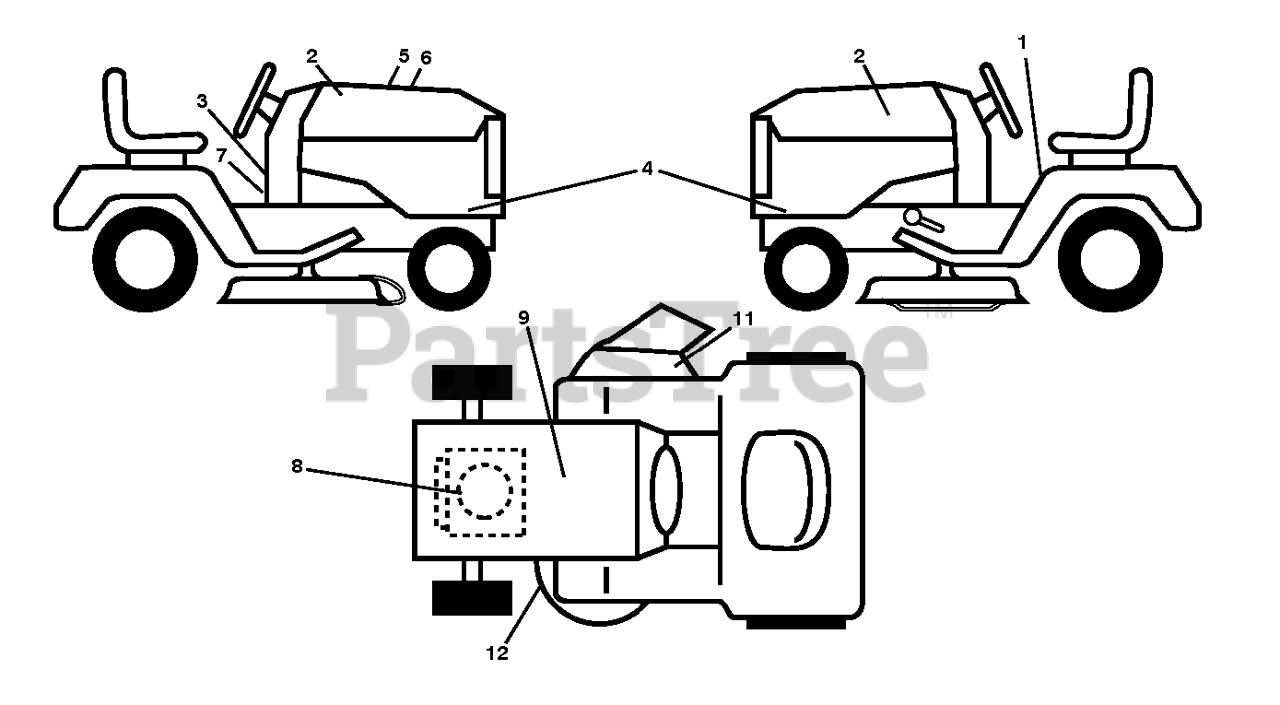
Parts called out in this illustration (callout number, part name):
1	DECAL.FENDER.WARNING
2	DECAL.BADGE.170MM.TEXTLOGO.
3	LABEL.EMISS.CA.HUSQ/LOWES.2011
4	RP DECAL.SDPNL.HUSGT2.YTH2042.
5	DECAL.WARNING.CUST.RESP.E85.
7	DECAL, WARNING SPARK ARRESTOR
8	DECAL.ENG.BS.20HPXRD.SL.278416
9	DECAL BTRY SYMBOLS
11	DECAL.WARN.KEEP.HAND.AWAY
12	DECAL V BELT SCHEMATIC
